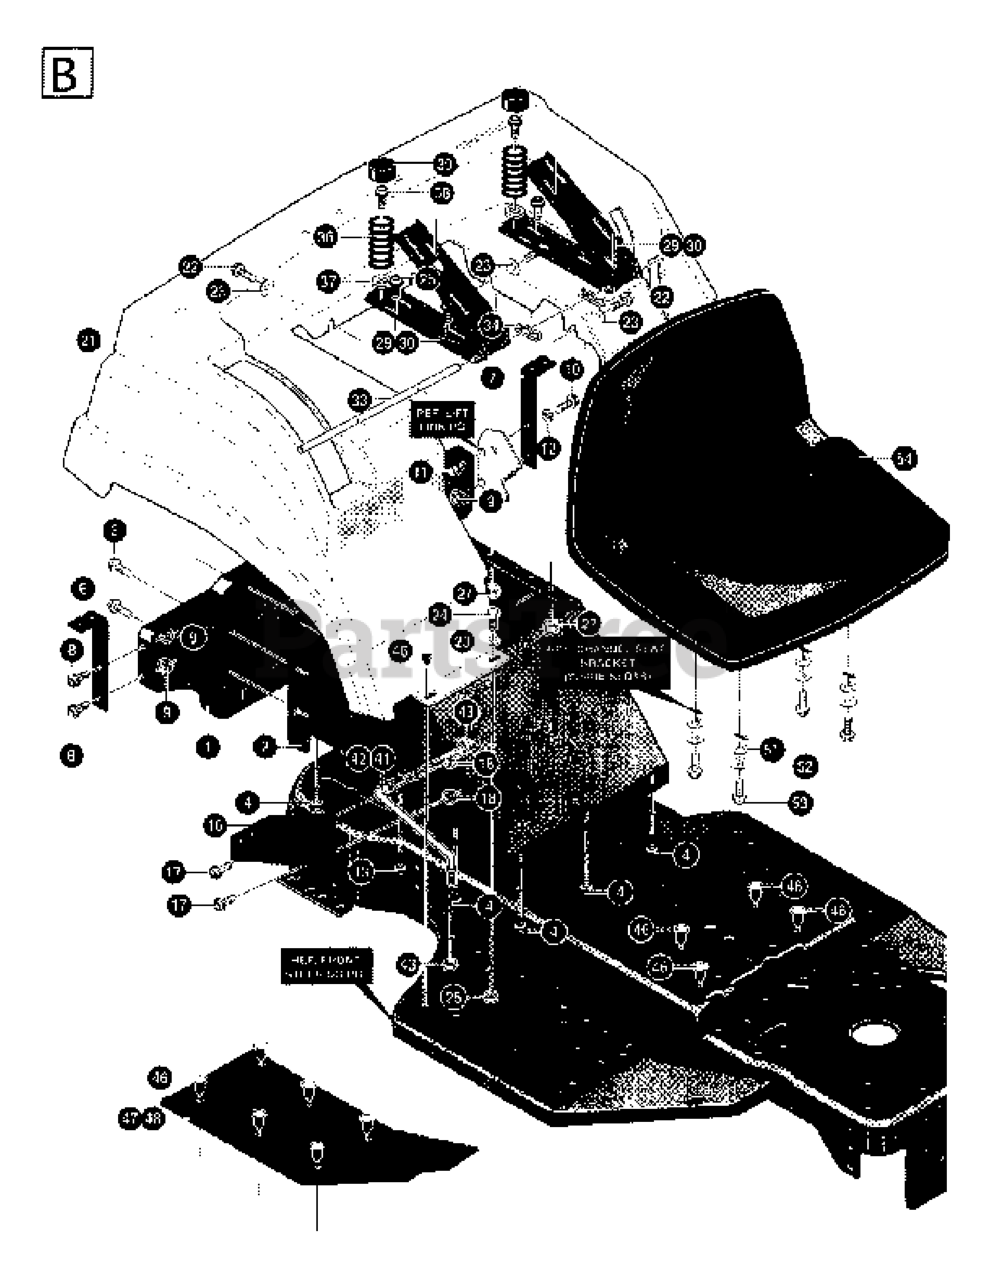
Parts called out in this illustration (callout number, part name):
3	SCREW
4	SCREW
8	SCREW
11	NUT
12	WASHER
13	SCREW
16	REPL BY 533 30 62-93
17	SCREW
22	SCREW
23	WASHER - M6
25	NUT
26	SCREW
27	NUT
37	WASHER
38	SCREW
39	CAP
43	NUT
51	WASHER
52	WASHER
53	SCREW
